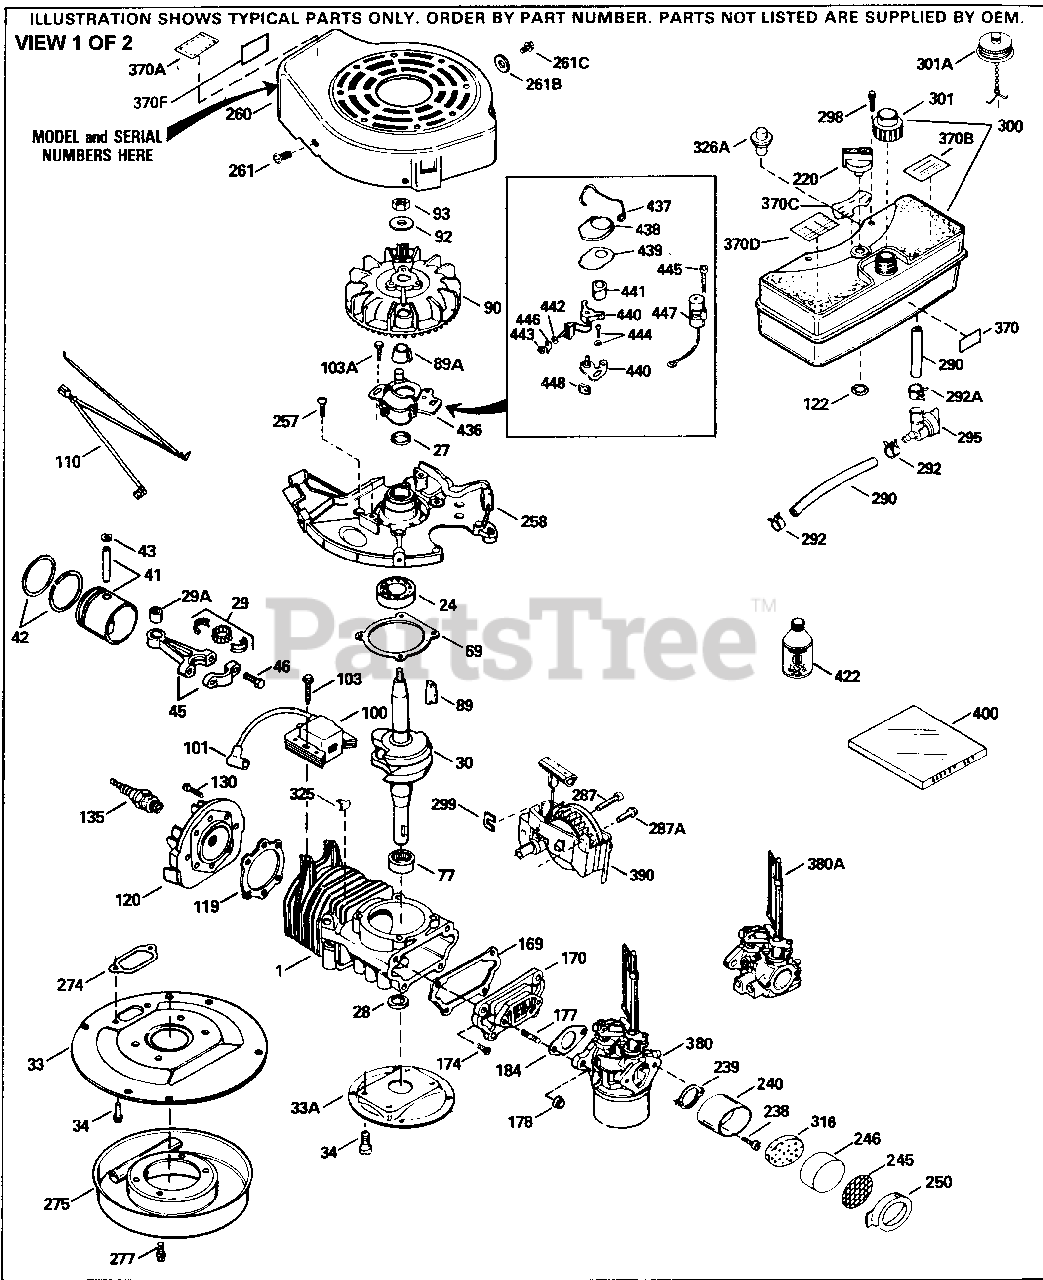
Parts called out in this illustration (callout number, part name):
1	"Cylinder Order s/b if replacement is req.
24	Ball Bearing
27	Oil Seal
28	Oil Seal
29	Needle Bearing & Liner Set 30 Needle s
29A	Cartridge Bearing
30	Crankshaft & Rod Ass'y. (Incl. 45)
30	Adapter Plate (8" B.C.)
34	Screw, 5/16-18 x 1/2"
41	Piston & Pin Ass'y. (Std.)(Incl. 43)
41	Piston & Pin Ass'y. (.010" OS)
42	Ring Set (Std.)
42	Ring Set (.010" OS)
43	Piston Pin Retaining Ring
45	Connecting Rod Ass'y. Incl. 29, 29A & 46
46	Connecting Rod Bolt
69	* Cylinder Cover Gasket
77	Cartridge Bearing
89A	Adapter Sleeve
90	Flywheel
92	Belleville Washer
93	Flywheel Nut
100	Solid State Ignition (Incl. 101)
100	Magneto to Solid State Conversion Kit (Includes solid state module, solid state flywheel key, and instructions. )(Use as required on external ignitio n engines only.)
101	Spark Plug Cover
103	Screw, Torx T-15, 10-24 x 1"
110	Ground Wire
119	* Cylinder Head Gasket
120	Cylinder Head
130	Screw, Torx T-30, 1/4-20 x 3/4"
135	Resistor Spark Plug - RJ17LM
169	* Cover Plate Gasket
170	Reed & Cover Plate (Incl. 178)
174	Screw, Torx T-25, 10-24 x l/2"
178	Nut, 1/4-20
184	* Carburetor Gasket
238	Screw, Torx T-25, 10-32 x 5/8"
239	Air Cleaner Gasket
240	Air Cleaner Body
245	Air Filter
246	Air Filter
250	Air Cleaner Cover
257	Screw, 1/4-20 x 5/8"
258	Blower Housing Base (Incl. 27)
260	Blower Housing
261	Screw, 114-20 x 7/16"
261C	Screw, 1/4-20 x 1/2"
274	Exhaust Gasket
275	Muffler
277	Screw, Torx T-30, 1/4-20 x 5/8"
290	Fuel Line (8.62")
292	Fuel Line Clamp
298	Screw, 10-32 x 7/8"
299	Rope Retainer Staple
300	Fuel Tank (Incl. 301)
301	Fuel Cap
316	Air Filter
326A	Fuel Tank Plug
370	Solid State Decal
370A	Name Decal
370B	Warning Decal
370D	Fuel Mix Decal
380	Carburetor (Incl. 184) (Refer to Divi sion 5, Section A, page A1-42 or Fich e 23B,Grid F-13 for breakdown)
400	* Gasket Set (Incl. items marked *)
422	2-Cycle Oil with Fuel Stabilizer - 8 oz.
